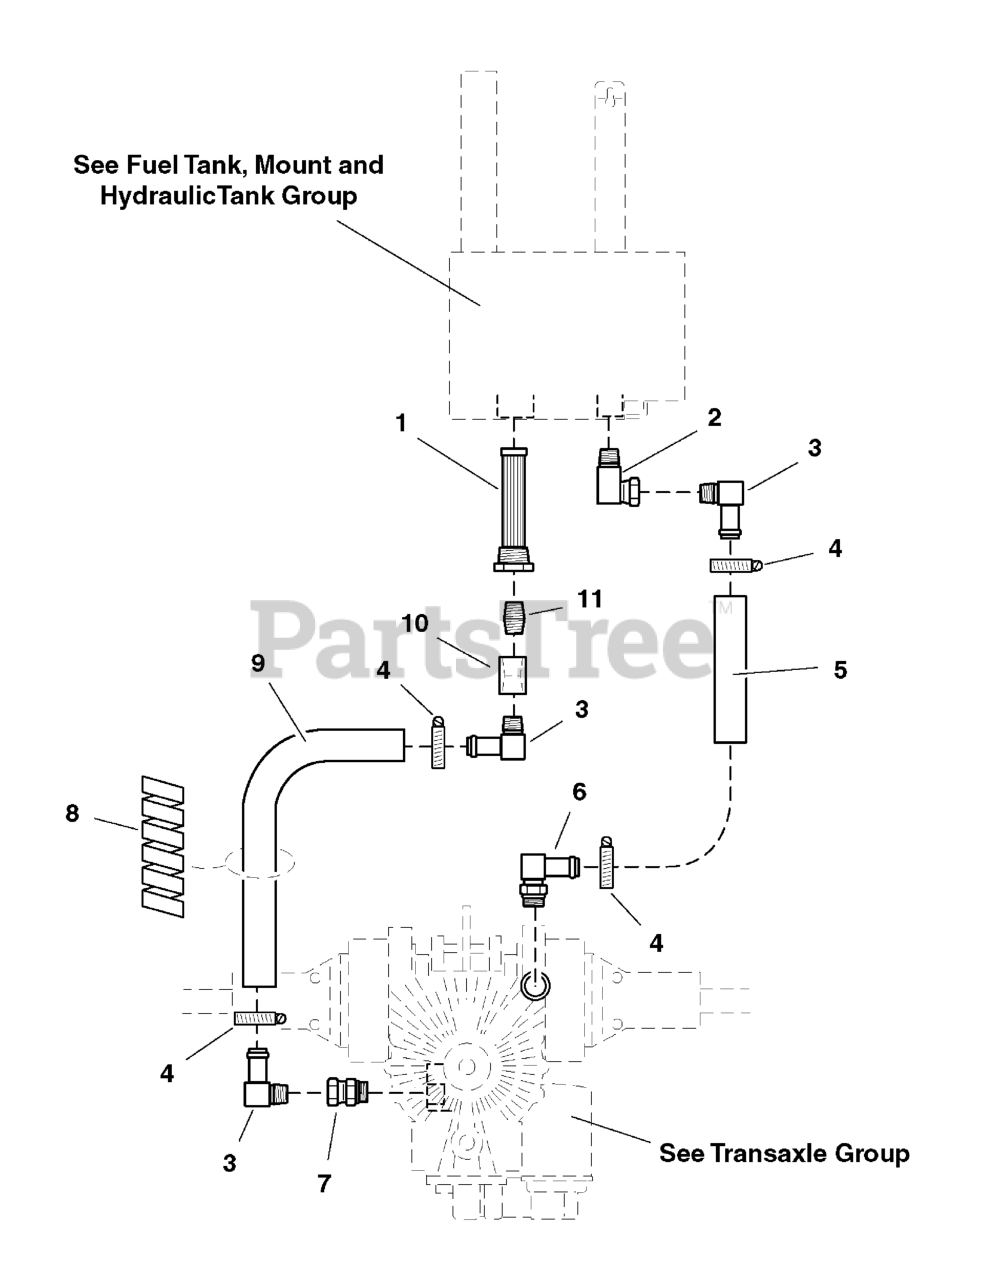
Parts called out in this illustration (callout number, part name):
1	STRAINER
2	FITTING, 1/2 NPT Swivel, 90 Deg.
3	FITTING, 90 Degrees 1/2" NPT
4	CLAMP, #10 Hose
5	Transmission Inlet Hose, 4.875" Long
6	FITTING, 90 Degrees 7/8" O-Ring
7	FITTING, 7/8" O-Ring Straight Swivel
8	PROTECTIVE COIL, 12"
9	HOSE, Transmission Return, 14.75"
10	COUPLER, 1/2" NPT
11	NIPPLE, 1/2" NPT Close
